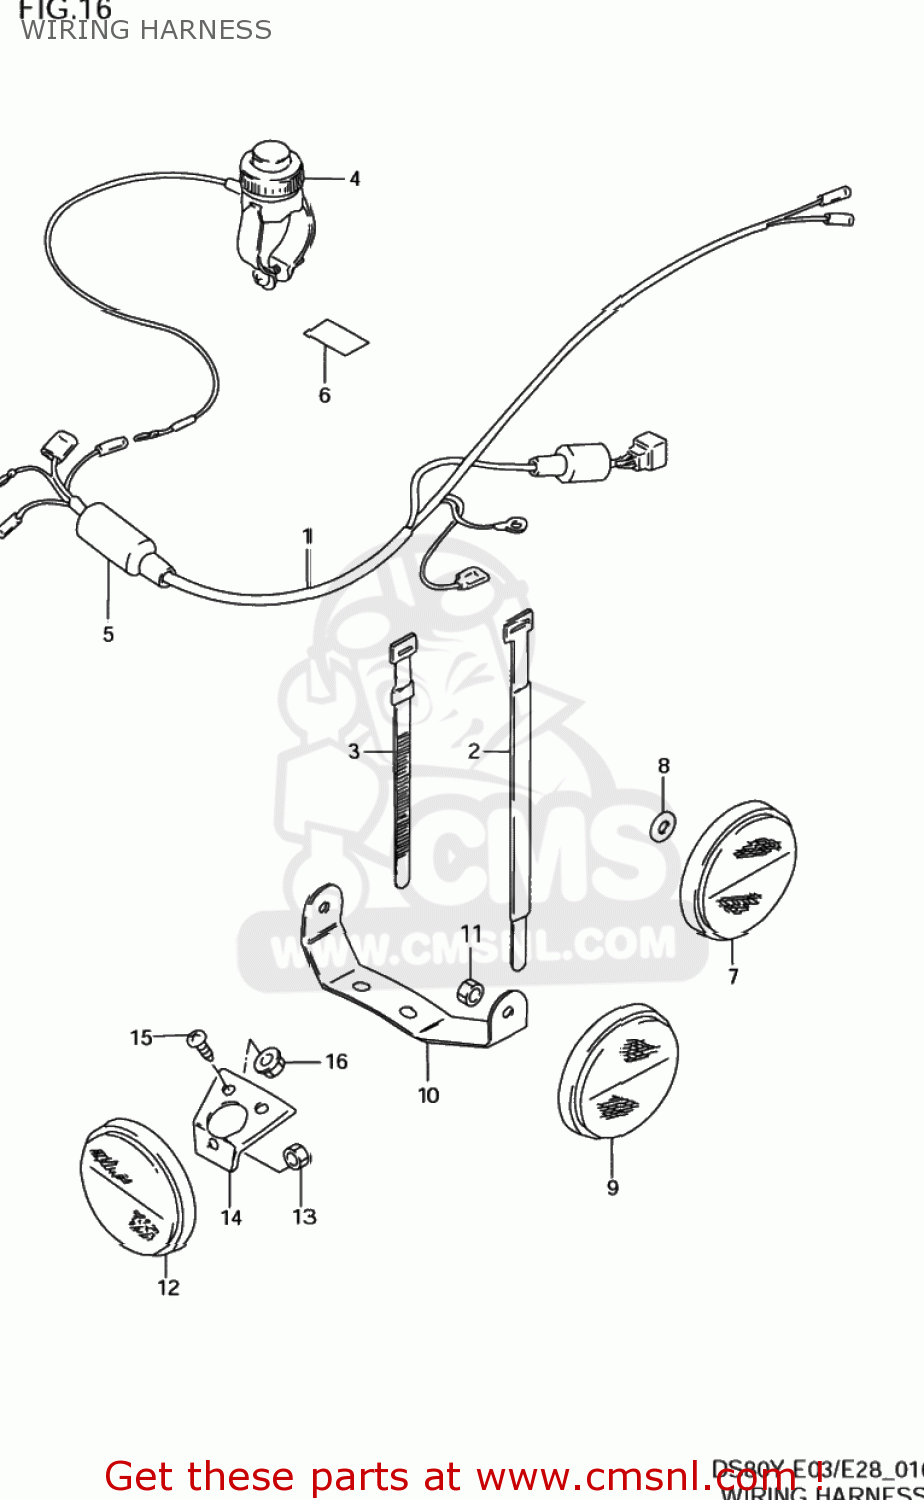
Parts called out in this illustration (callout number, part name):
1	HARNESS,WIRING
2	CLAMP(L:95)
3	CLAMP(L:120)
4	SWITCH ASSY,ENGINE STOP
5	COVER,WIRE
6	LABEL (ENGINE STOP)
7	REFLEX REFLECTOR,FR
8	WASHER
9	REFLEX REFLECTOR,RR
10	BRACKET,RR SIDE RR
11	NUT
12	REFLEX REFLECTOR,RR
13	NUT
14	BRACKET, REAR REFLECTOR
15	SCREW
16	NUT
